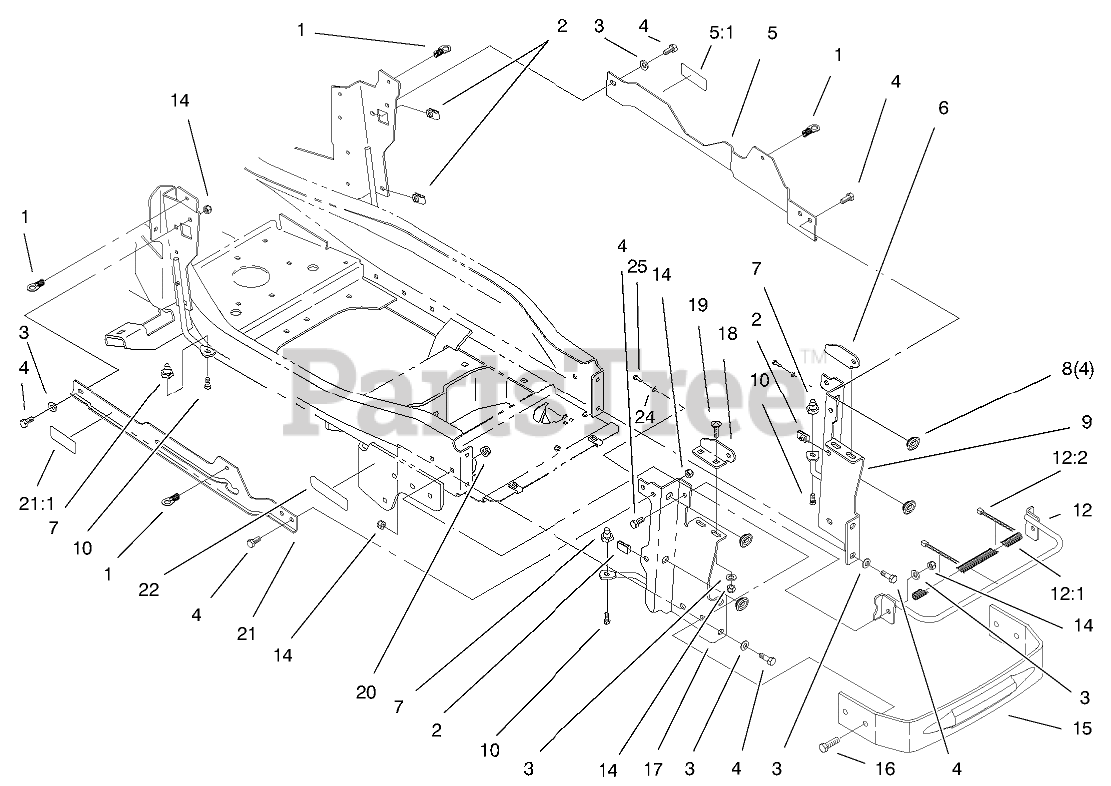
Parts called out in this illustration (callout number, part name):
1	LATCH ASM
3	WASHER-PLAIN
4	SCREW-HH
5	Support ASM (Only On: 73550)
5	Support ASM (Only On: 73551)
5:1	Decal-Warning (Only On: 73550)
5:1	Decal-Warning (Only On: 73551)
6	BRKT-LOWER HINGE LH (BLACK)
7	MOUNT-SIDEPANEL
8	GROMMET
9	SUPPORT-HOOD, LH
10	SCREW-PLASTITE
12	ASSEMBLY - HOOD SUPPORT
12:1	COVER-BRACE
12:2	TIE-CABLE
14	NUT-LOCK, NI
15	BUMPER-FRAME
16	SCREW-HH
17	SUPPORT-HOOD, RH
18	BRKT-LOWER HINGE RH
19	SCREW-CARR
20	NUT-LOCK, NI
21	Support ASM (Only On: 73550)
21	Support ASM (Only On: 73551)
21:1	Decal-Warning (Only On: 73550)
21:1	Decal-Warning (Only On: 73551)
22	DECAL-ATTACH A-MATIC
24	Washer-Flat (Only On: 73551)
25	Screw-HH TAP (Only On: 73551)
